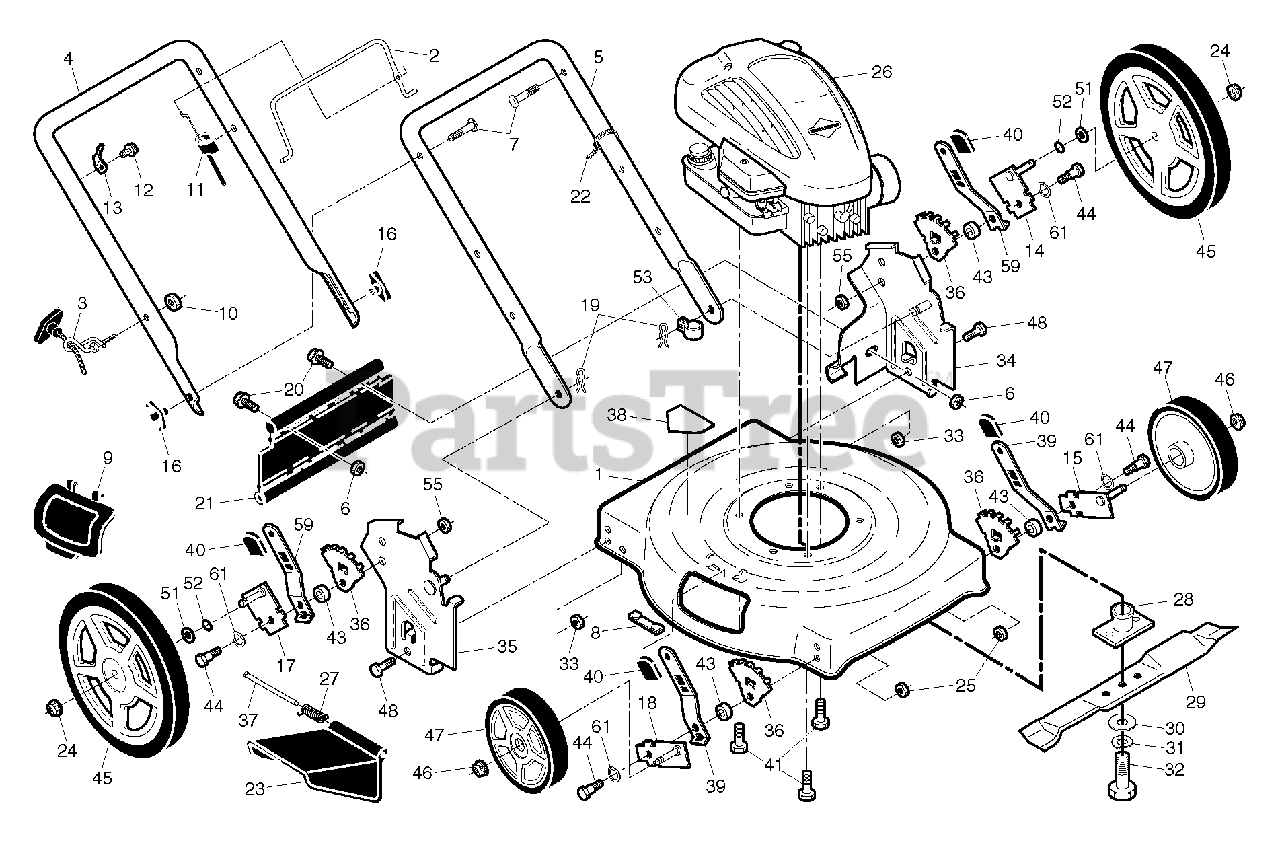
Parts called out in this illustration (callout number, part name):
1	KIT.HOUSING.22".PUSH.MARIGOLD
2	BAIL.CONT.D.STRAIGHT.PUSH.BLK
3	GUIDE.ROPE.STD.BLK.ZIN
4	HANDLE.UPPER.ECONOMY.BLACK
5	HANDLE.LOWER.D-STRAIT.BLACK
6	LOCKNUT.NYLOC.1/4-20
7	BOLT, HANDLE 5/16-18X1.75
8	CLIP. CLOSEOUT
9	PLATE.MULCHER.22.ECON.BLACK
10	NUT
11	CABLE.MZR.RATO.22"LOW.
13	BRACKET.UPSTOP.RT
14	Axle Arm Assembly, .Lr.5/9.Pos.Bzp
15	AXLE ARM ASSY FRONT LH
16	KNOB.WING.PLASTIC.BLACK
17	Axle Arm Assembly, RR 5/9 Pos BZP
18	AXLE ARM ASSY FRONT RH
19	HAIRPIN COTTER
20	BOLT.HEX.1/4.X.3/4.DICHROMATE
21	SKIRT.REAR.22RD/SD.FO/VE
22	TIE GUIDE
23	GUARD.DISCHARGE.22".
24	NUT.HEX.FLANGE.3/8-16.LOCKNUT
25	NUT.FLANGE.HEX.5/16X18.BLACK
26	ENGINE.RATO.550S.140C
27	SPRING.HINGE
28	ADAPTER.BLADE.W/KEY.25MM.CE
29	BLADE.22.MULCH.STANDARD
30	WASHER,HARDEN
32	BOLT.3/8-24X1.25 GR8
33	NUT.71038.31-18.HEX.NYLOCK
34	BRKT.ASM.HDL.22.ECON.BLACK
35	BRKT.ASM.HNDL.22.ECON.HW.RH.BL
36	WHEEL ADJ BRACKET FRONT
37	HINGE ROD
38	No Step Decal
39	SELECTOR SPRING, FRONT
41	BOLT 3/8-16X1-1/8
43	SPACER.HEIGHT.ADJUSTER
44	SHOULDER BOLT 5/16-18
45	WHEEL.12X1.75.5SPK.BRK.GRN.
46	NUT.HEX.FLANGE.3/8-16.LOCKNUT
47	WHEEL.7X1.75.5SPK.BRK.GREEN
51	WASHER PM
52	O-RING..070X.487.NEOPRENE
55	NUT.LOCK.5/16-18
59	SPRING.SEL.EXT.21.DOMED.12/14
61	WASHER.CURVED.CYLINDRICAL
